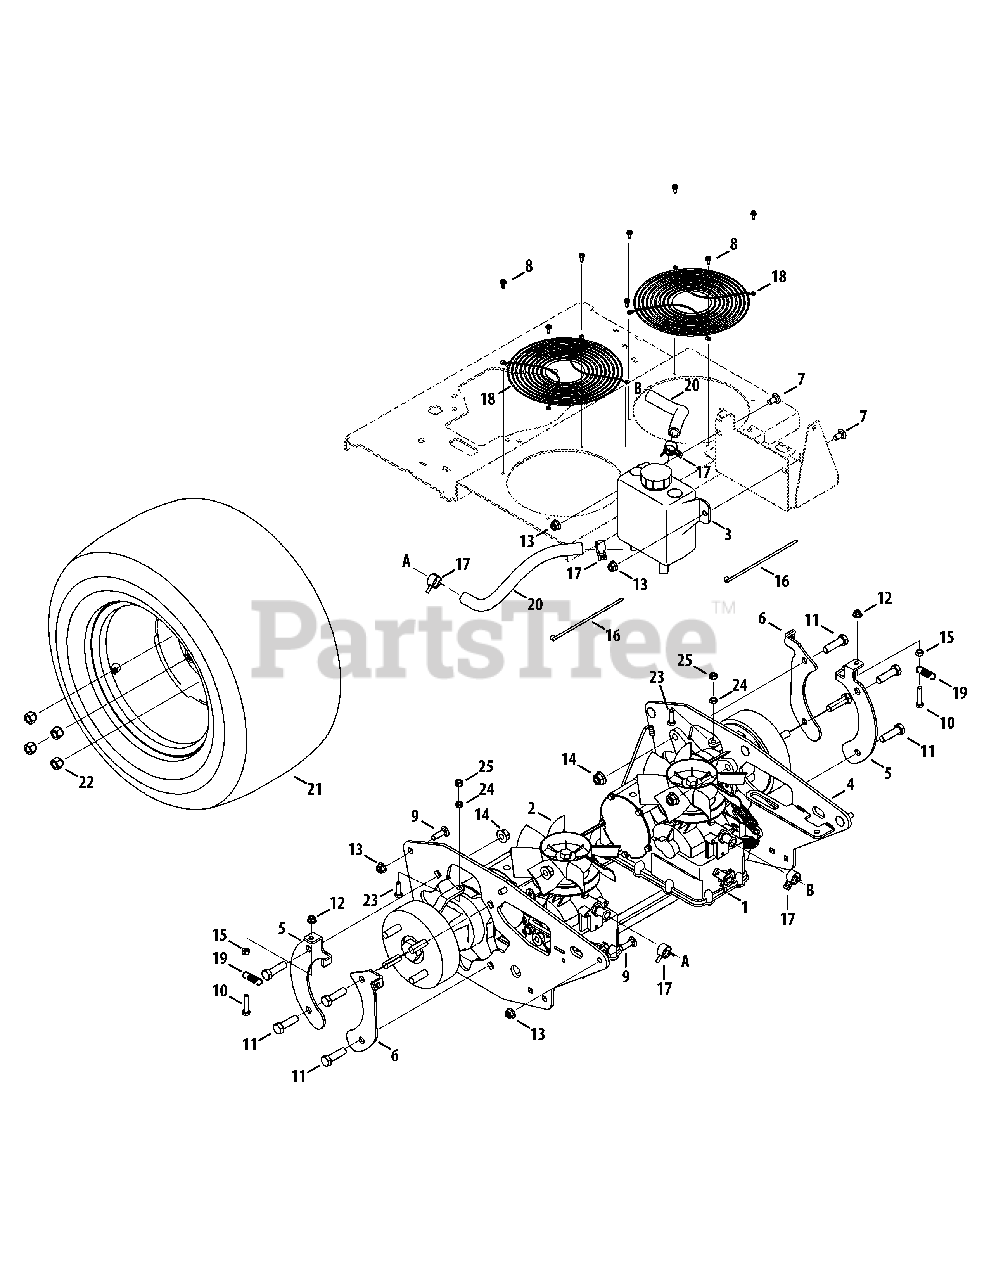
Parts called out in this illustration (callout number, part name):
1	Transmission, LH
2	Transmission, RH
3	Hydro Tank Assembly
4	Transmission Bracket Assembly
5	Spring Brake Mounting Bracket
6	Brake Cable Mounting Bracket
7	Carriage Bolt, 3/8-16 x .75
8	Screw, 10-24 x .500
9	Carriage Bolt, 3/8-16 x 1.25
10	Hex Cap Screw, 5/16-18 x 1.50
11	Hex Cap Screw, 1/2-13 x 1.75
12	Nut, 5/16-18, Flangelock
13	Nut, 3/8-16, Flangelock
14	Nut, 1/2-13, Flangelock
15	Nut, 5/16-18, Hex
16	Cable Tie
17	Hose Clamp, .9375
19	Extension Spring, .50 OD x 1.71
20	Hose, 5/8 ID x 12.00 LG
21	Wheel Assembly, 24 x 12-12
22	Lug Nut, 1/2-13
23	Hex Cap Screw, 5/16-18 x 1.00
24	Jam Nut, 5/16-18
25	Nut, Hexlock 5/16-18
